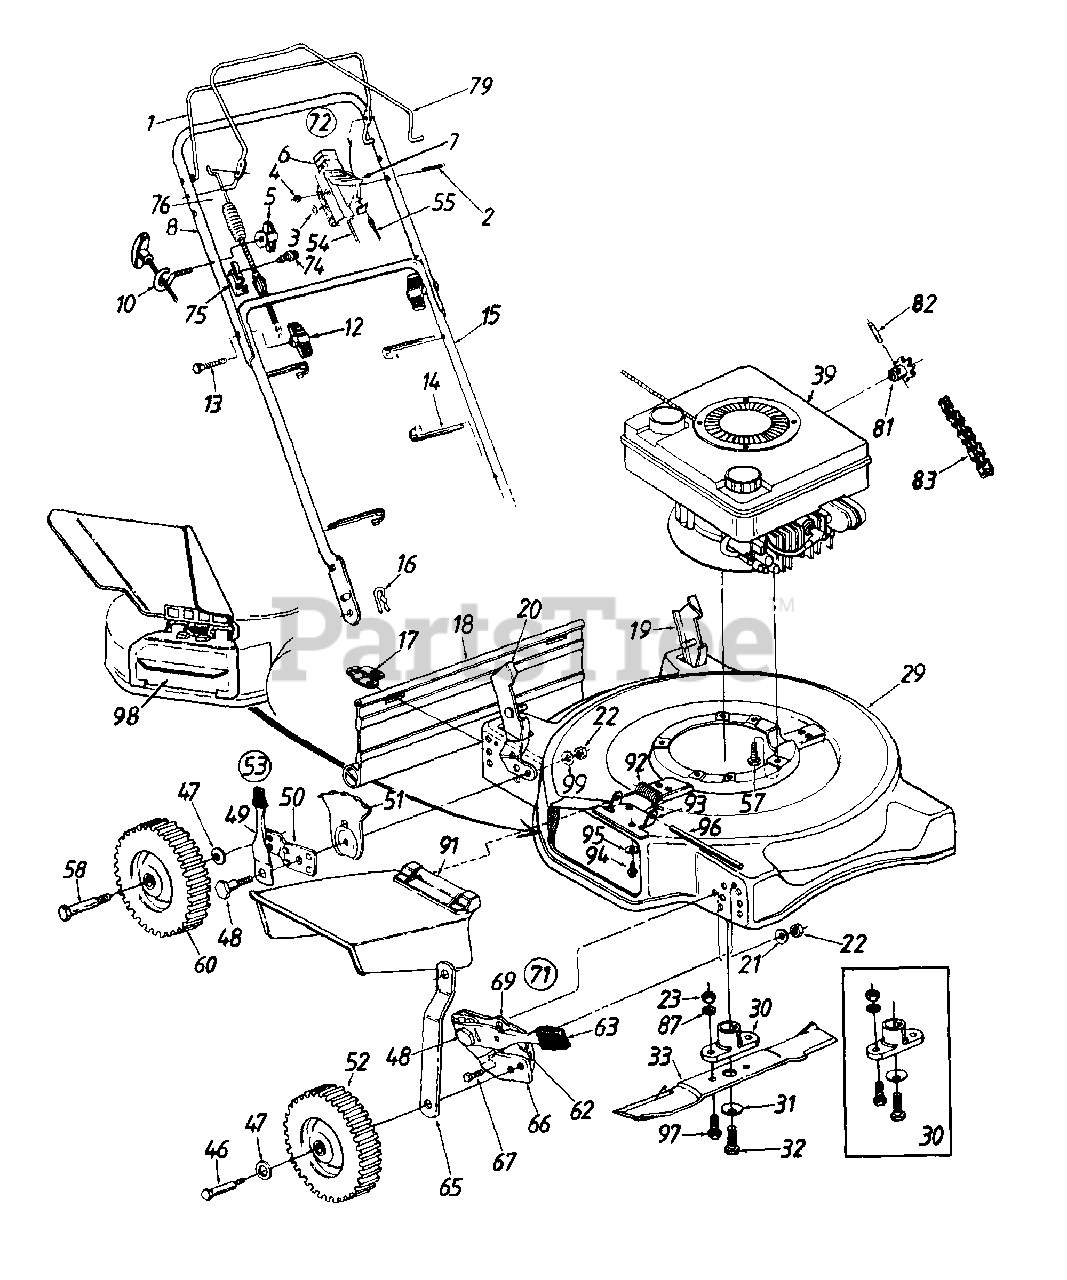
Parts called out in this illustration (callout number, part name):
2	Oval C-Sunk Mach. Scr.
3	Spr. Wash .66" I.D.
4	Hex L-Nut 1/4-20 Thd.
5	Handle Knob 1/4-20 Thd.
6	Throttle Body
7	Throttle Lever
12	Hand Knob
13	Curved Hd. Bolt 5/16-18 x 2" Lg.
14	Cable Tie
16	Hairpin Cotter
17	Hinge Clip
18	Rear Flap
22	Hex Nut 3/8-16 Thd.
23	Hex Nut 3/8-24 Thd.
29	22" Deck Ass'y.
30	Blade Adapter Kit
31	Bell-Wash .39" I.D.
32	Hex Bolt 3/8-24 x 1.5" Lg.
33	22" Blade
39	Engine
46	Front Axle Bolt
47	Bell-Wash .400" I.D. x .88"
48	Shld. Bolt .50" Dia. x .357"
49	Spring Lever Ass'y. w/Knob
51	Height Adj. Plate
52	Front Wheel Ass'y. Comp.
53	Height Adj. Ass'y. Comp.- R.H.
54	Throttle Control Wire - 45"
55	Control Cable - 51"
57	Hex L-Wash. Hd. Scr. 3/8-16 x 1.0" Lg.
58	Rear Axle Bolt
60	Rear Wheel Ass'y. Comp.
62	Spring Lever
63	Spring Lever Knob
67	Hex AB-Tap 1/4-.62" Lg.
69	Index Plate
71	Front Height Adj. Ass'y.- R.H.
72	Throttle Box Comp.
74	Hex Wash. AB-Tap Scr. 5/16 x .75" Lg.
75	Cable Brkt.
76	Clutch Cable w/Spring - 47"
82	Spring Pin Spir. 3/16" Dia. x 1" Lg.
83	#48 Chain 1/2" Pitch 50 Links (Endless)
87	L-Wash. 3/8" I.D.
91	Chute Deflector Ass'y.
92	Torsion Spring
93	Adapter Plate
94	Hex Self-Tap Scr. 1/4-20 x .5" Lg.
95	Bell-Wash. 1/4" I.D.
96	Hinge Pin
97	Hex Bolt 3/8-24 x 1" Lg.
98	Mulching Plug
99	Bell-Wash .39" I.D. x 1.38" O.D.
